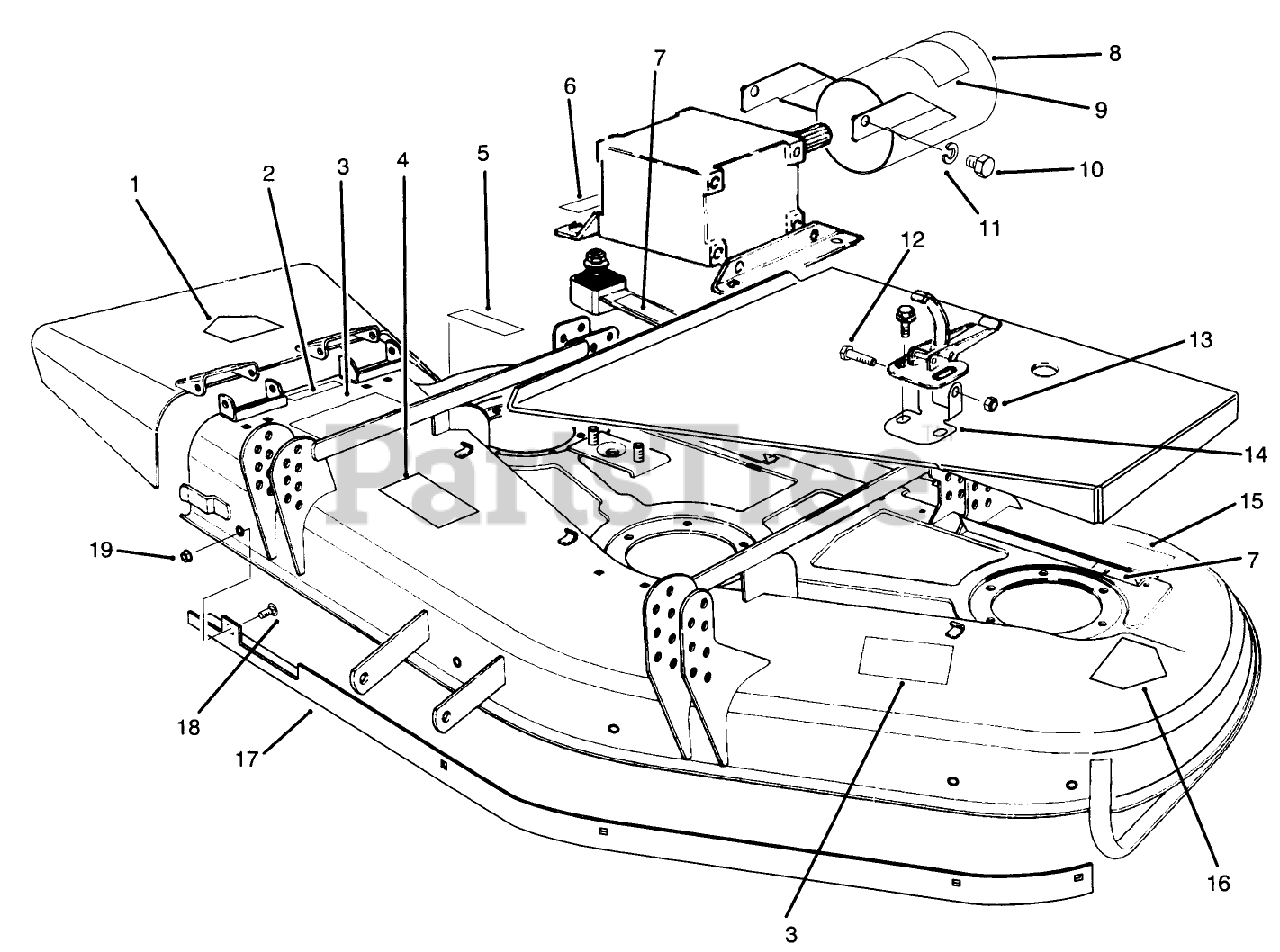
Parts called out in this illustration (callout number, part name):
1	DECAL-DANGER
2	DECAL-WARNING, DEFLECTOR
3	DECAL-DANGER
4	DECAL - WARNING
5	DECAL BLANK
6	DECAL-LUBE
7	DECAL-DANGER
8	Guard-PTO Shaft
9	DECAL-DANGER
10	SCREW-HH
11	WASHER-LOCK
12	SCREW-HH
13	NUT-LOCK, NI
14	RETAINER-LATCH
15	DECAL-TORQUE, BLADE BOLT
16	DECAL-DANGER, INT'L
17	Baffle
18	SCREW-CARR
19	NUT-HF
